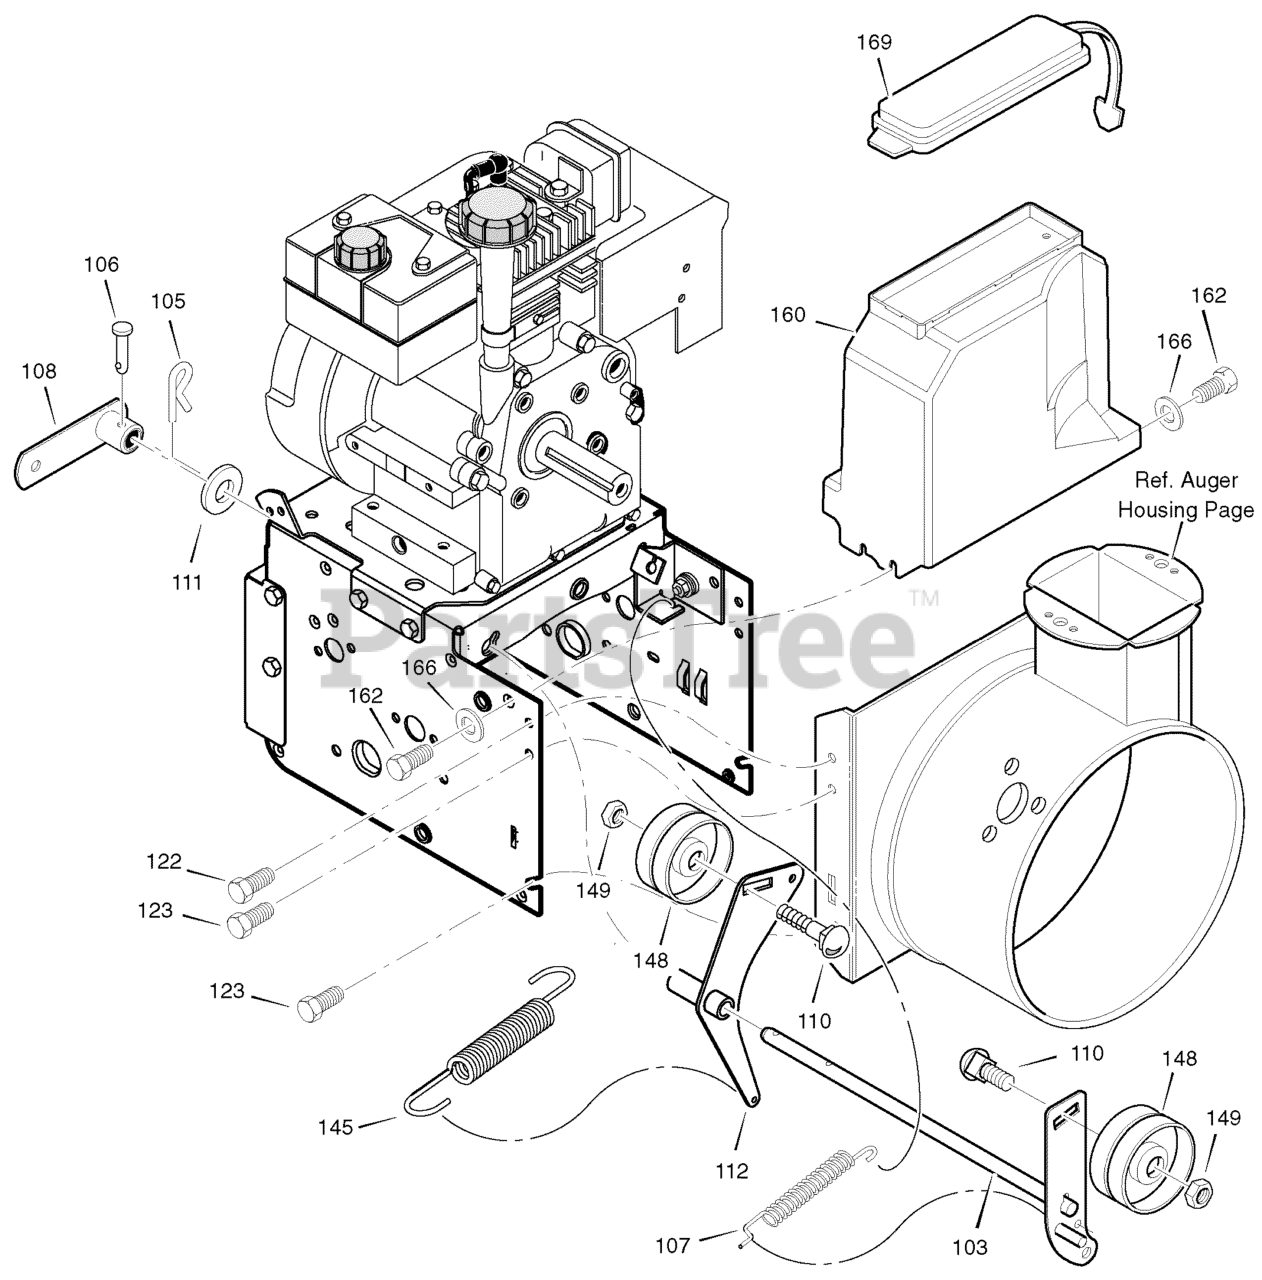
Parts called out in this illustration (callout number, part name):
103	IDLER ASSEMBLY, AUGER
105	PIN, HAIR .38DIAX1.64LG
106	PIN, CLEVIS 3/16" DIA
107	SPRING, TENSION
108	ASSY., SPRING ATTACH
110	BOLT, 3/8-16X1.25 CARR.
111	WASHER, FLAT
112	BRACKET, IDLER
122	SCREW, TAP 5/16-18 X .75
123	SCREW, TAP 5/16-18 X .50
145	SPRING, CLUTCH
148	PULLEY, IDLER
149	NUT, JAM 3/8-16
160	COVER, BELT
162	SCREW, TAP
167	WASHER, FLAT
169	LID, TOOL BOX
